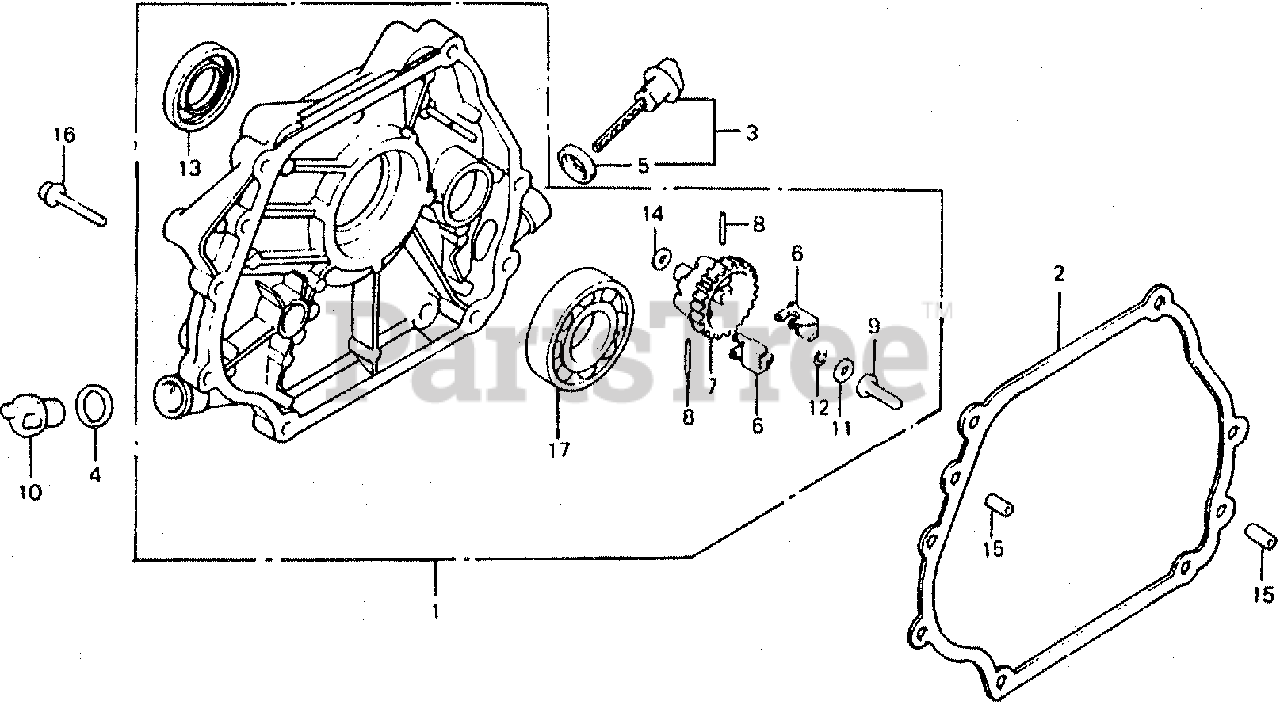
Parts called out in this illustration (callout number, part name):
1	COVER ASSY., CRANKCASE (WK-TYPE)
1	COVER ASSY., CRANKCASE
2	GASKET, CASE COVER
3	CAP ASSY., OIL FILLER
4	GASKET, OIL FILLER CAP
5	GASKET, OIL FILLER CAP
6	WEIGHT, GOVERNOR
7	HOLDER, GOVERNOR WEIGHT
8	PIN, GOVERNOR WEIGHT
9	SLIDER, GOVERNOR
10	CAP, OIL FILLER
10	CAP, OIL HOLE
11	WASHER (6X16)
12	CLIP, GOVERNOR HOLDER
13	OIL SEAL (30X45X8)
14	WASHER, PLAIN (6MM)
15	PIN A, DOWEL (8X14)
16	BOLT, FLANGE (8X35)
17	BEARING, RADIAL BALL (6206)
